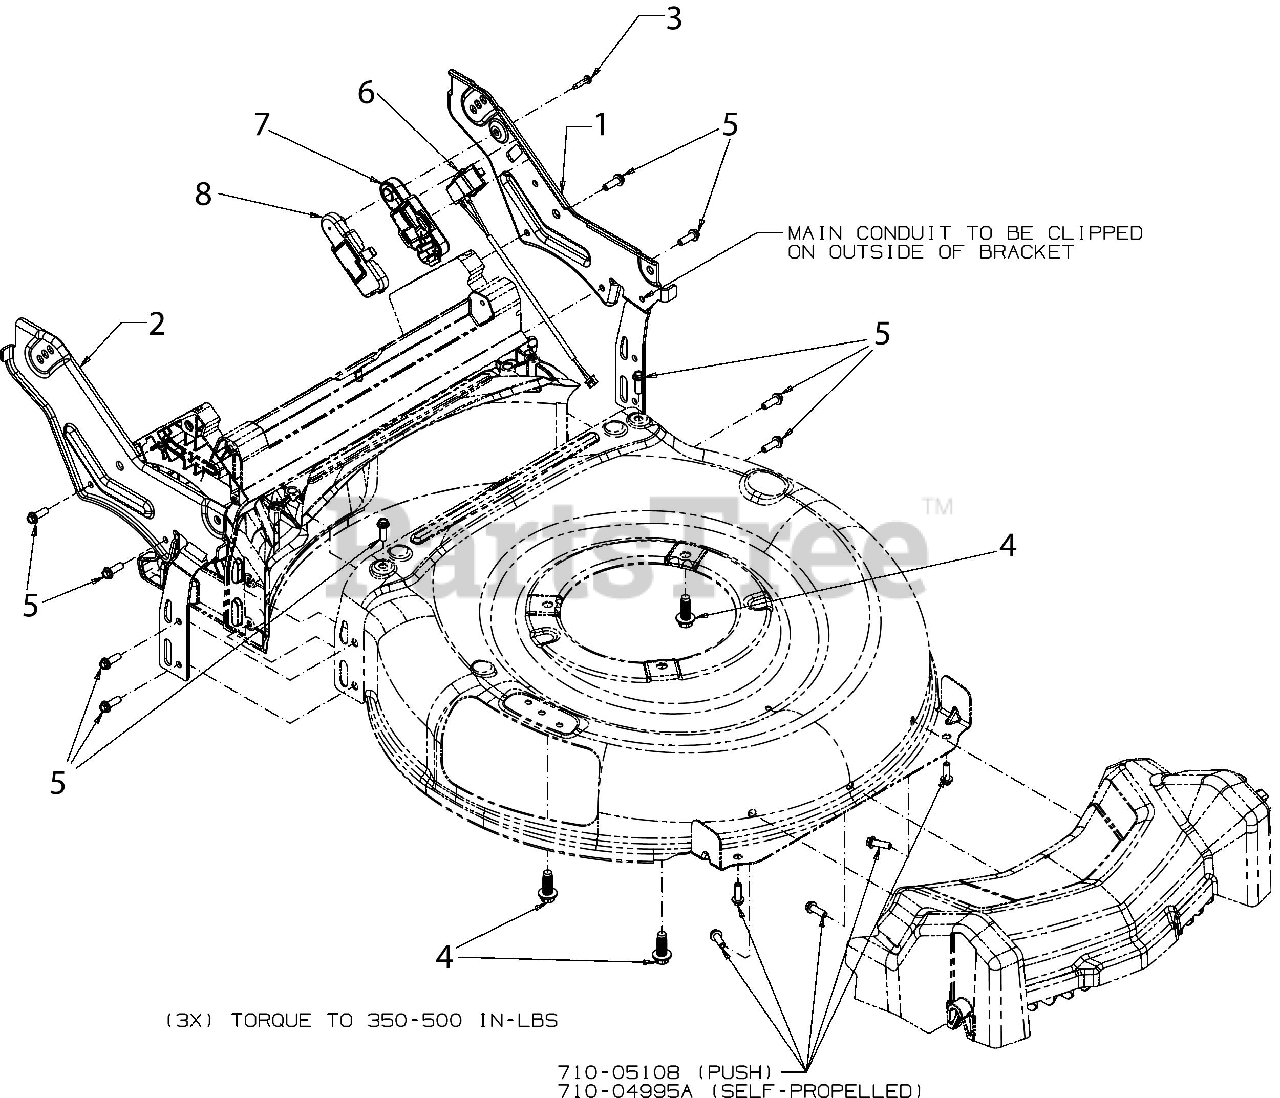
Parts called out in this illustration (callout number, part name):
3	SCREW 7-18X.75:T20
4	SCREW 3/8-16 x 1
5	SCREW 1/4 x .750
6	ROCKER SWITCH
7	UPPER HOUSING HANDLE SWITCH
8	LOWER HOUSING HANDLE SWITCH
